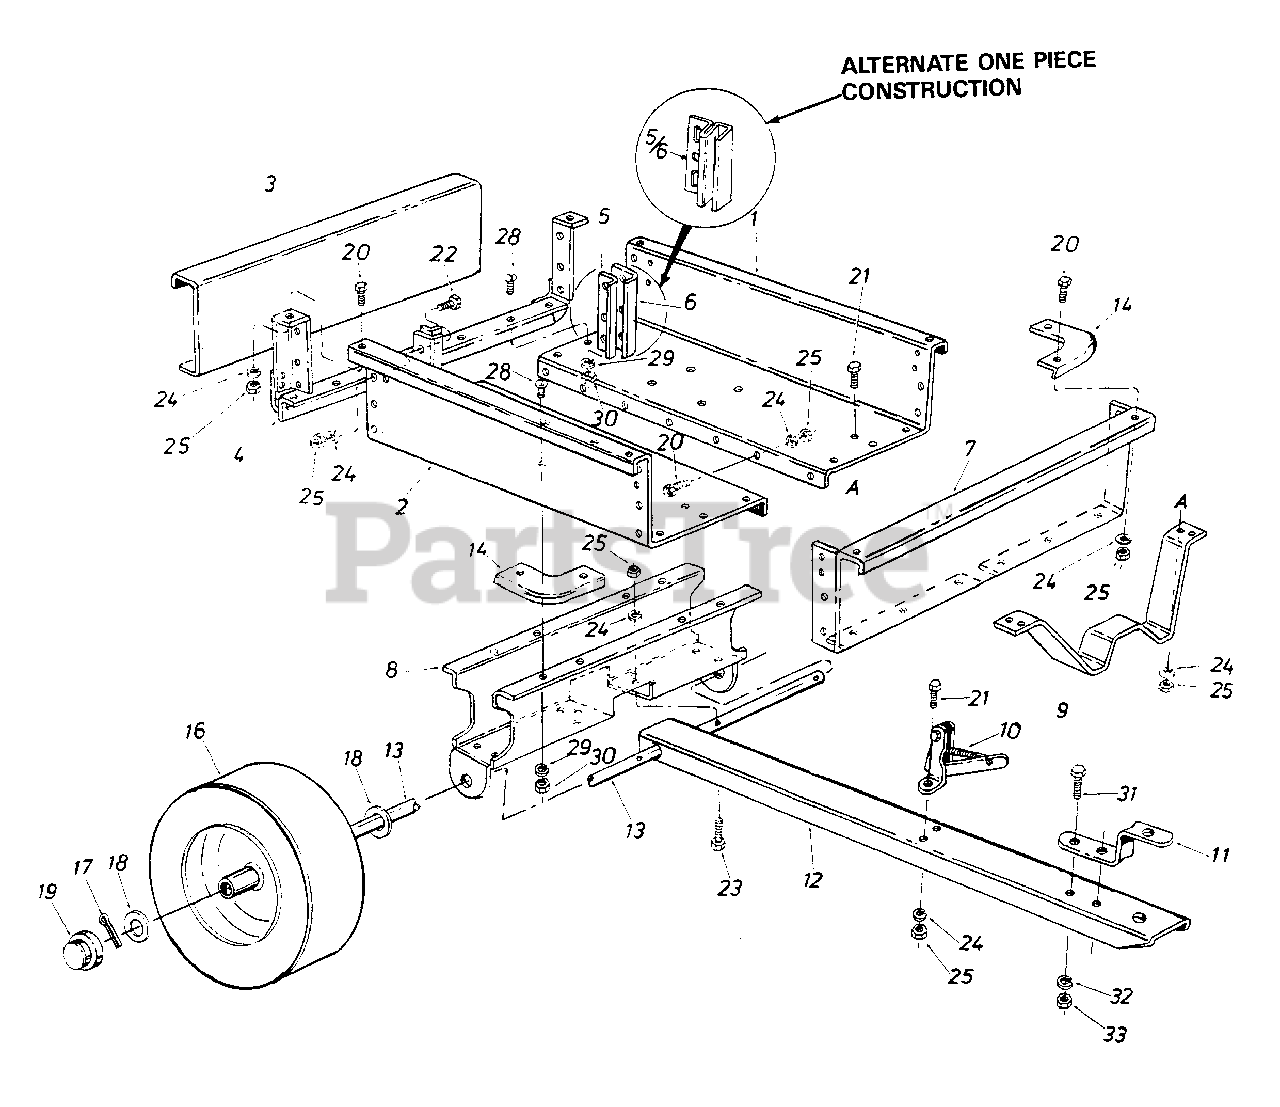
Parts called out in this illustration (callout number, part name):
1	Cart Body
3	Tailgate
4	Sub-Ass'y., Rear Angle
5	Guide, Tailgate - Inside
5	Guide, Tailgate - One Piece
6	Guide, Tailgate - Outside
7	Front Panel
8	Wheel Support
9	Latch Stand Bracket
10	Ass'y. Latch Lock
11	Hitch Bracket
12	Draw Bar Tongue
13	Wheel Axle 3/4" Dia.
13	Wheel Axle 1" Dia.
14	Cap, Front Corner
16	Wheel, 4.30 x 3.75
16	Wheel, 16/6.50 x 8.00
17	Cotter Pin 1/8" Dia. x 1" Lg.
17	Cotter Pin 1/8" Dia. x 1-1/2" Lg.
18	Washer, Flat 25/32" I.D.
18	Washer, Flat 1.032" I.D.
19	Hub Cap
20	Hex Bolt 1/4" x 1/2" Lg.
21	Hex Bolt 1/4" x 5/8" Lg.
22	Hex Bolt 1/4" x 3/4" Lg.
23	Hex Bolt 1/4" x 1-1/2" Lg.
23	Hex Bolt 1/4" x 1-3/4" Lg.
24	Lock Washer 1/4" I.D.
25	Hex Nut 1/4" Thread
28	Slotted Truss Head Bolt 5/16" x 3/4" Lg.
29	Lock Washer 5/16" I.D.
30	Hex Nut 5/16" Thread
31	Hex Bolt 3/8" x 1" Lg.
32	Lock Washer 3/8" I.D.
33	Hex Nut 3/8" Thread
